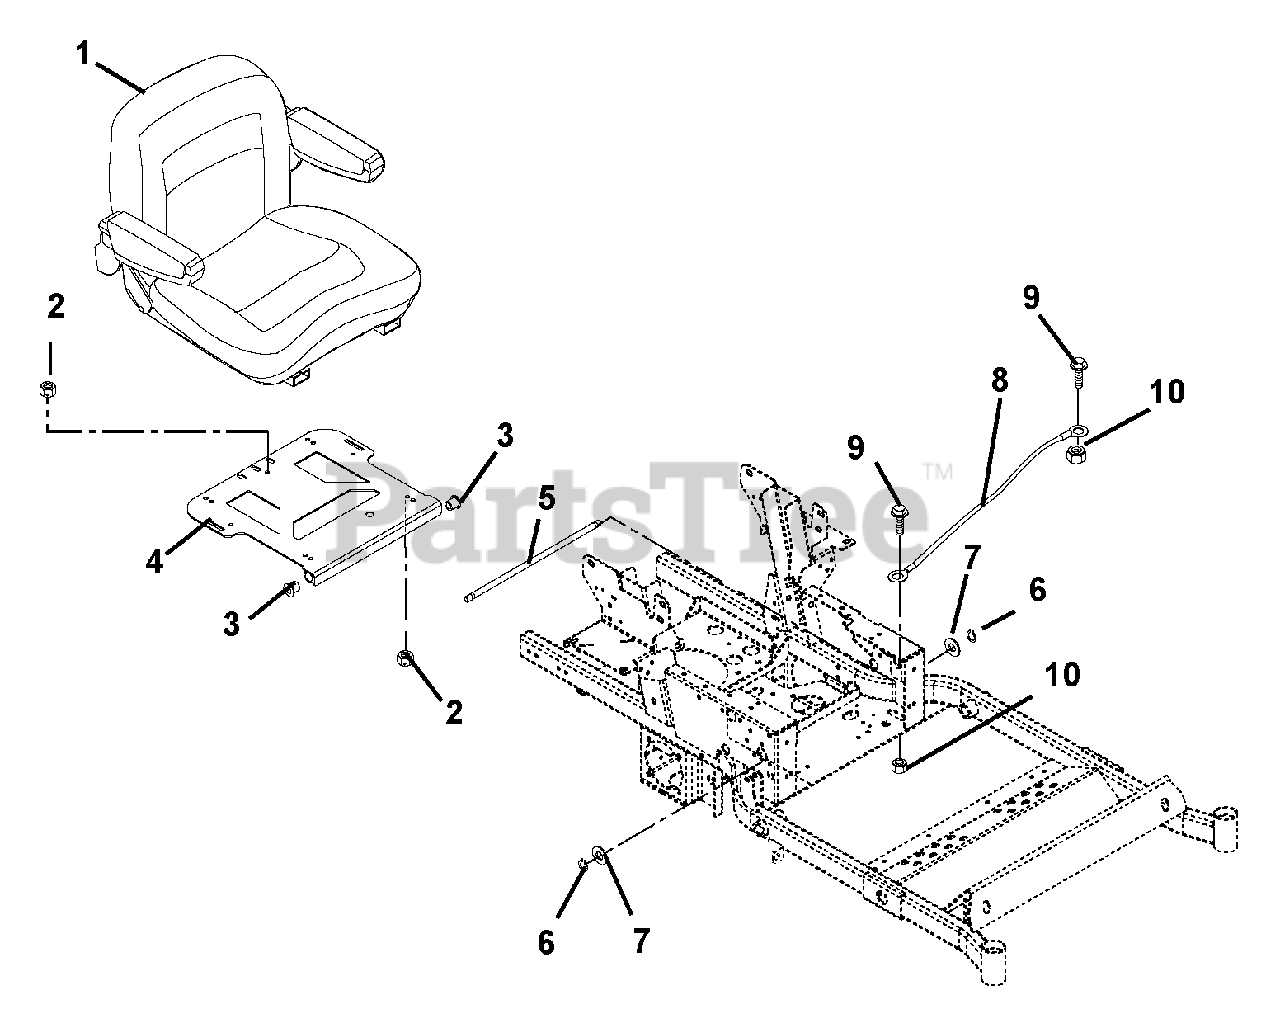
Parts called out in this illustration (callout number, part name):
1	SEAT, MILSCO XB180 - ZOOM
2	@NUT-LK-TOP-FLG .31-18 YWZC
3	BSHG-FLG .515X.750X.745X1.00NY
4	WMT, SEAT PIVOT MOUNT
5	ROD, SEAT FRAME PIVOT
6	RG-RTNG-EXT .500X.050 (SNAP)
7	WSHR-FL-STL.531X1.00X.063 YWZC
8	CBL,HOOD
9	@BLT-HEX .25-20X.75 GR5 YWZC
10	@NUT-LK-TOP-FLG .25-20 YWZC
